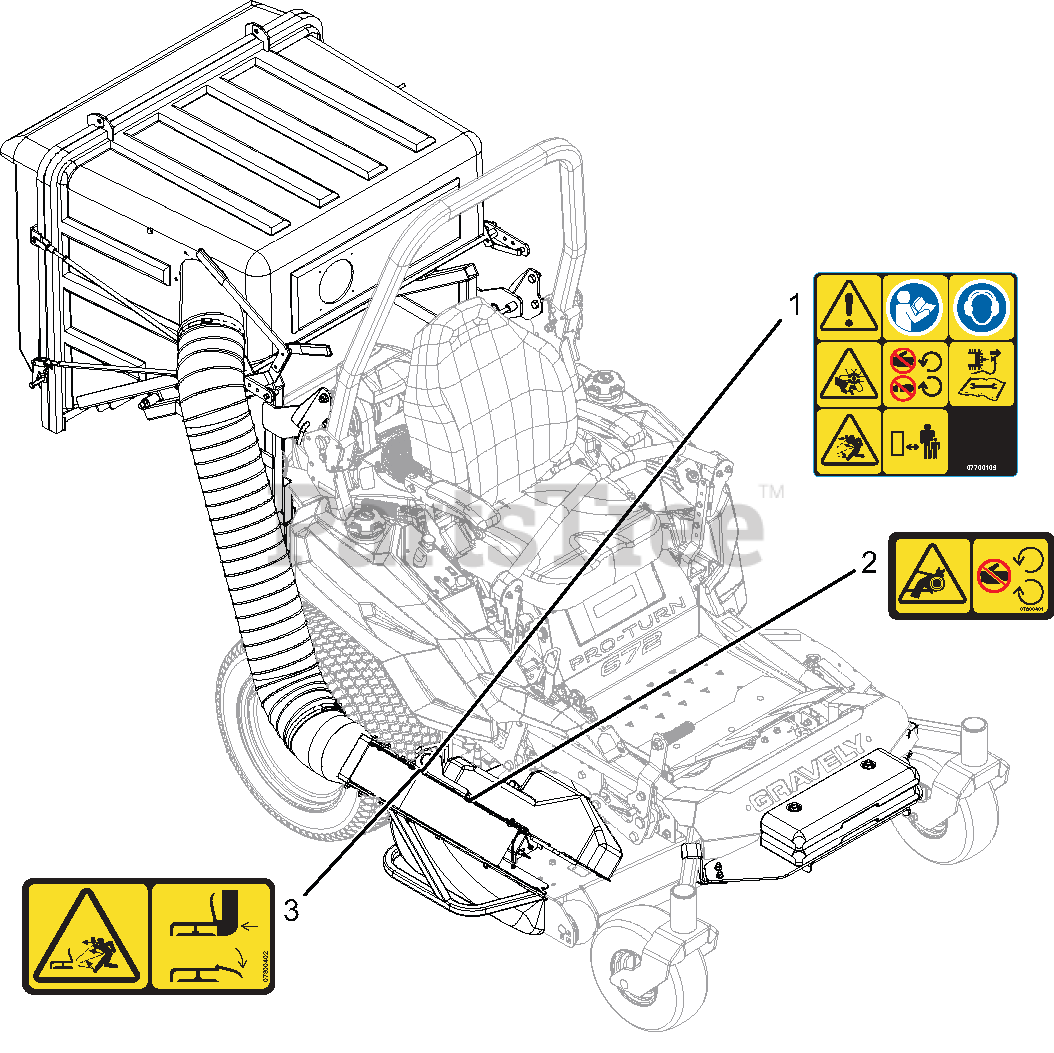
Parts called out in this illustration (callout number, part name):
1	DECAL,VAC WARNING ISO
2	DECAL, SAFETY - GUARDING
3	DECAL, SAFETY - DECK GUARDING
